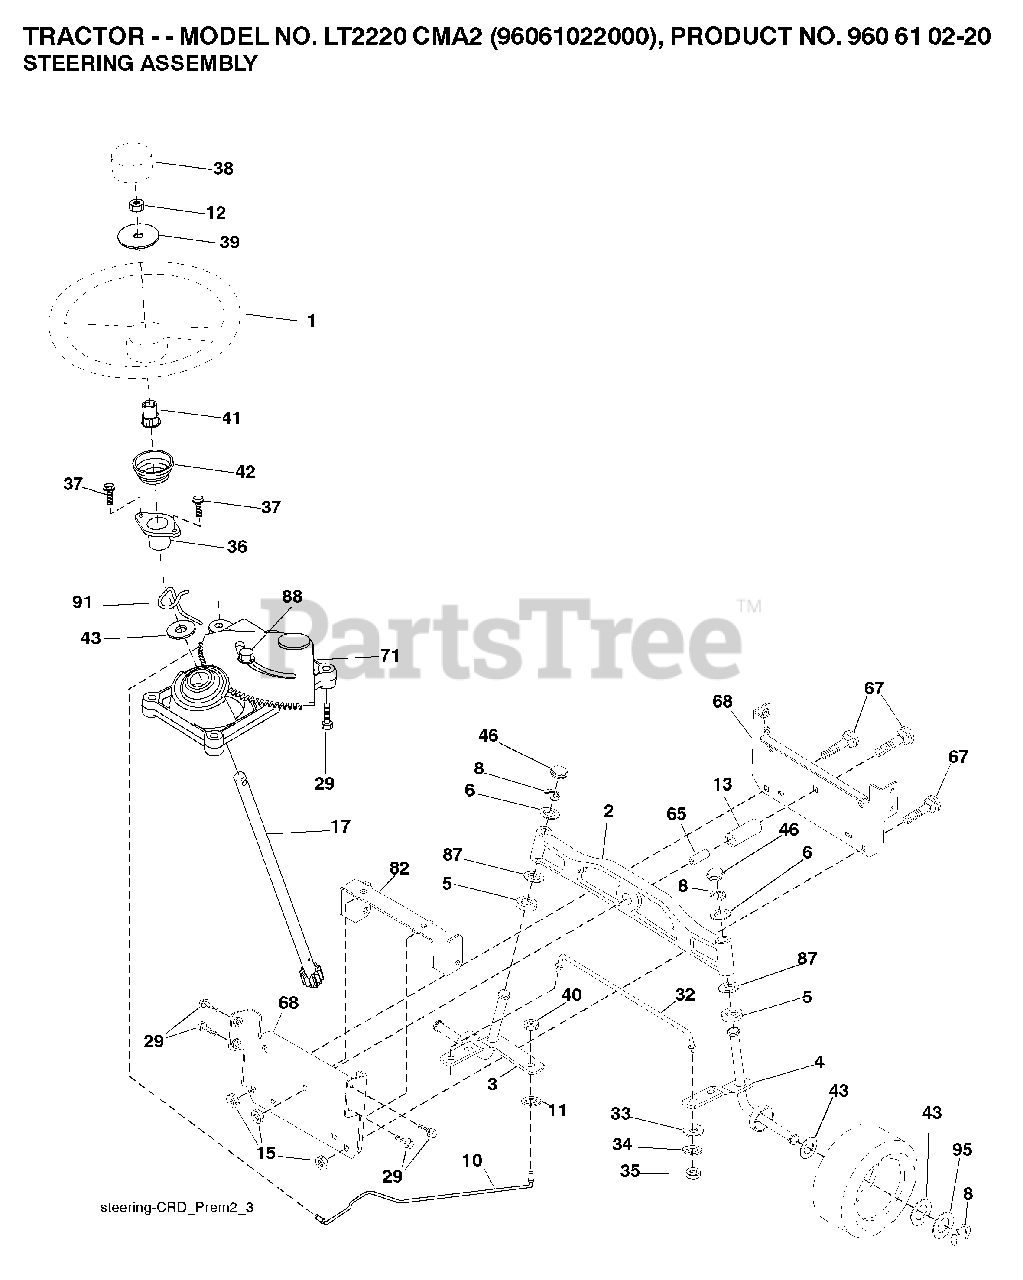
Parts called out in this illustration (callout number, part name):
1	WHEEL.STEERING.PREM.2.BLK
2	AXLE ASSY FRONT
3	SPINDLE.ASM.LH.15"TIRES
4	SPINDLE.ASM.RH.15"TIRES
8	RING CLIP
10	DRAGLINK.15".TIRES.2001
11	WASHER, LOCK 3/8
12	NUT.HEX.1/2-20
13	TUBE, PIVOT AXLE
15	NUT
17	SHAFT ASM STRG
29	SCREW, 3/8-16X3/4
33	WASHER M
34	LOCKWASHER
35	NUT, CROWNLOCK
36	BUSHING, STRG. BLK
38	INSERT.CAP.STRG.WH.BLACK
39	WASHER 9/16"ID, 2 3/8"OD
40	NUT CROWNLOCK 3/8-24
41	ADAPTER, WHEEL STNG..
46	CAP.SPINDLE
65	SPACER BRACE AXLE
67	BOLT CARRIAGE
68	BRACE.AXLE.15"TIRES
71	STEERING ASM
82	BRACKET.SUSP.CHASSIS.FRONT.15
87	WASHER, FLAT .781 X 1 1/2"
88	BOLT, SHOULDER 7/16-20
91	CLIP.STEERING
95	WASHER.HARDENED
